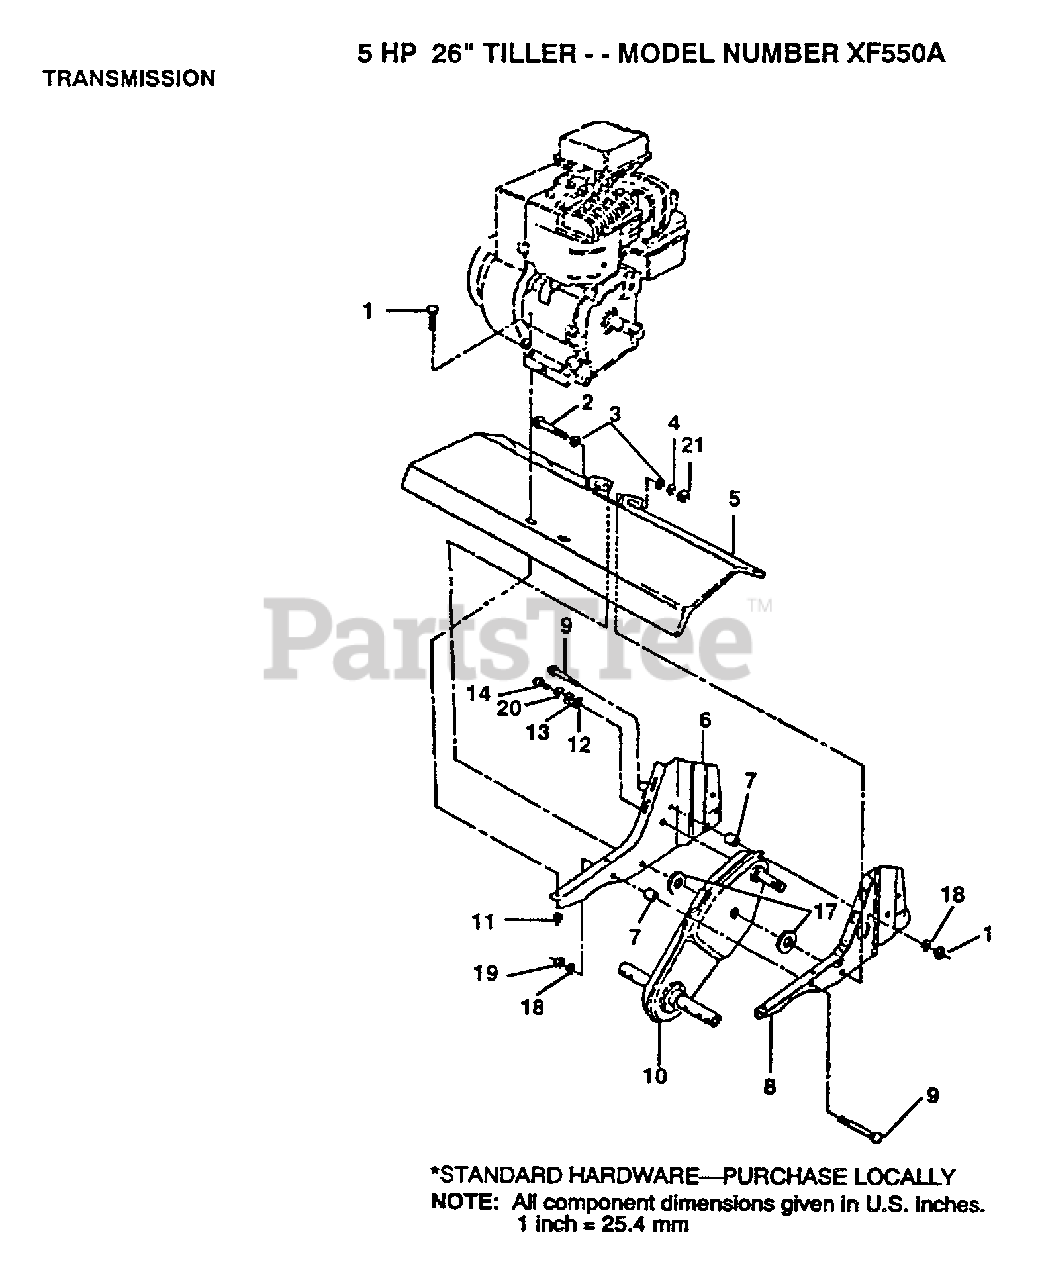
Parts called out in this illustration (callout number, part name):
1	BOLT.HEX.5/16-1.5
2	BOLT.3/8-24X3.75
3	WASHER
4	LOCKWASHER
5	"SHIELD,TINE "
7	SPLIT SPACER RT
8	BRACKET.ENG.LH.
12	WASHER
13	WASHER
14	BOLT
18	LOCKWASHER
19	NUT.HEX.5/16-18
20	LOCKWASHER
21	GRIPCO NUT
